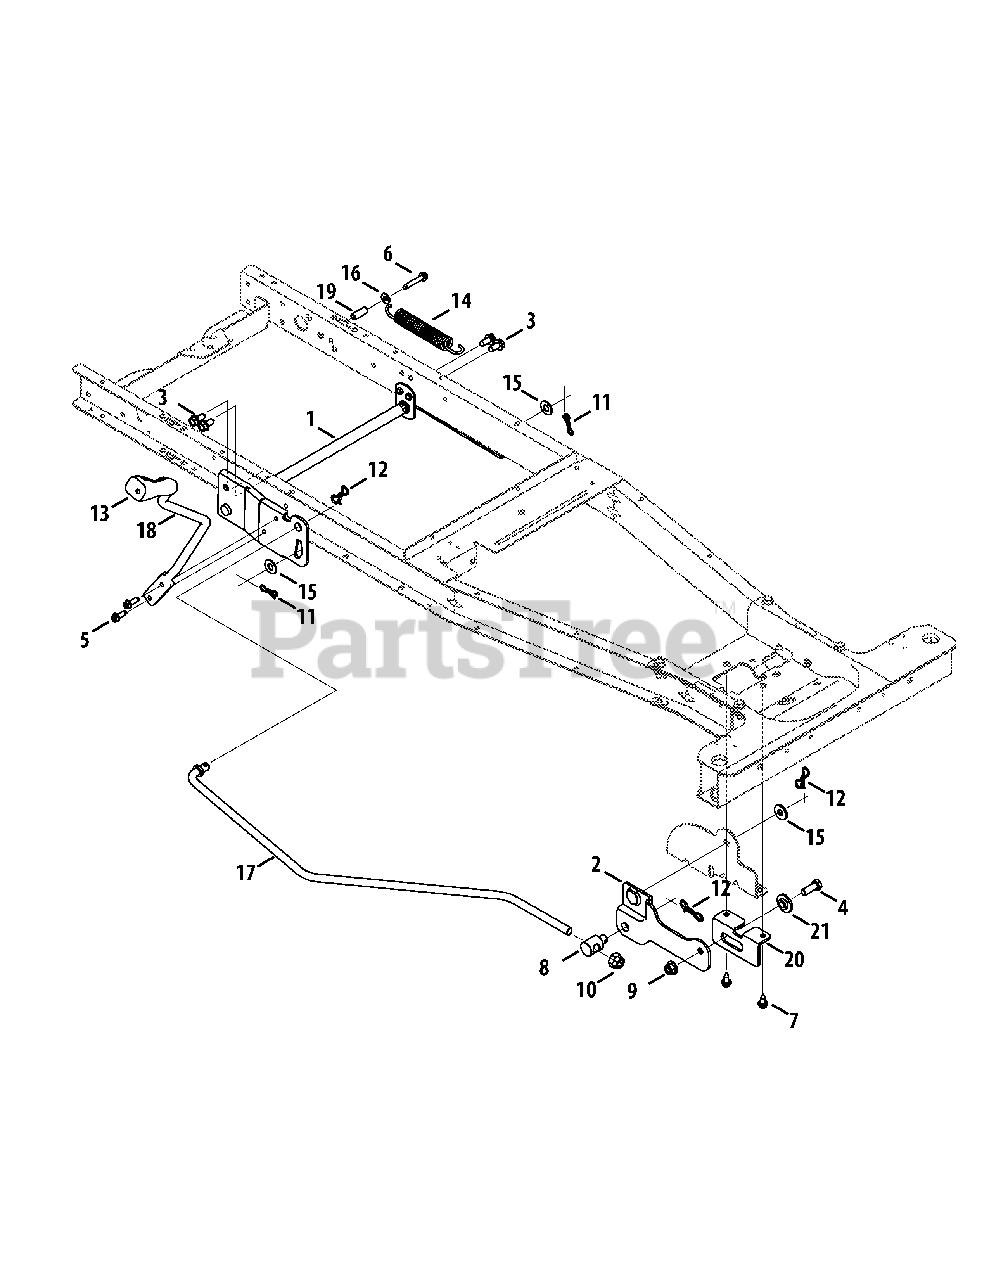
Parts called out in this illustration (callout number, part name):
1	Lift Assembly Shaft
2	Front Hanger Bracket Assembly
3	Tap Screw, 5/16-18, .750
4	Hex Head Screw, 3/8-16, 1.00
5	Tap Screw, 1/4-20, 0.750
6	Tap Screw, 1/4-20, 1.50
7	Tap Screw, 1/4-20 X .625
8	Ferrule, .50 X .50
9	Flange Lock Nut, 3/8-16
10	Flex Lock Nut, 1/2-13
11	Bow-Tie Cotter Pin, 72
12	Bow-Tie Cotter Pin, 91
13	Grip Handle, 1/2
14	Extension Spring, .85 OD X 5.915 LG
15	Flat Washer, .406 X .875 X .059
16	Flat Washer, .250 X .630 X .052
17	Lift Link Rod
18	Deck Lift Rod
19	Spacer, .260 x .375 x 1.030 LG
20	Front Deck Mounting Bracket
21	Shoulder Spacer, .625 x .169
